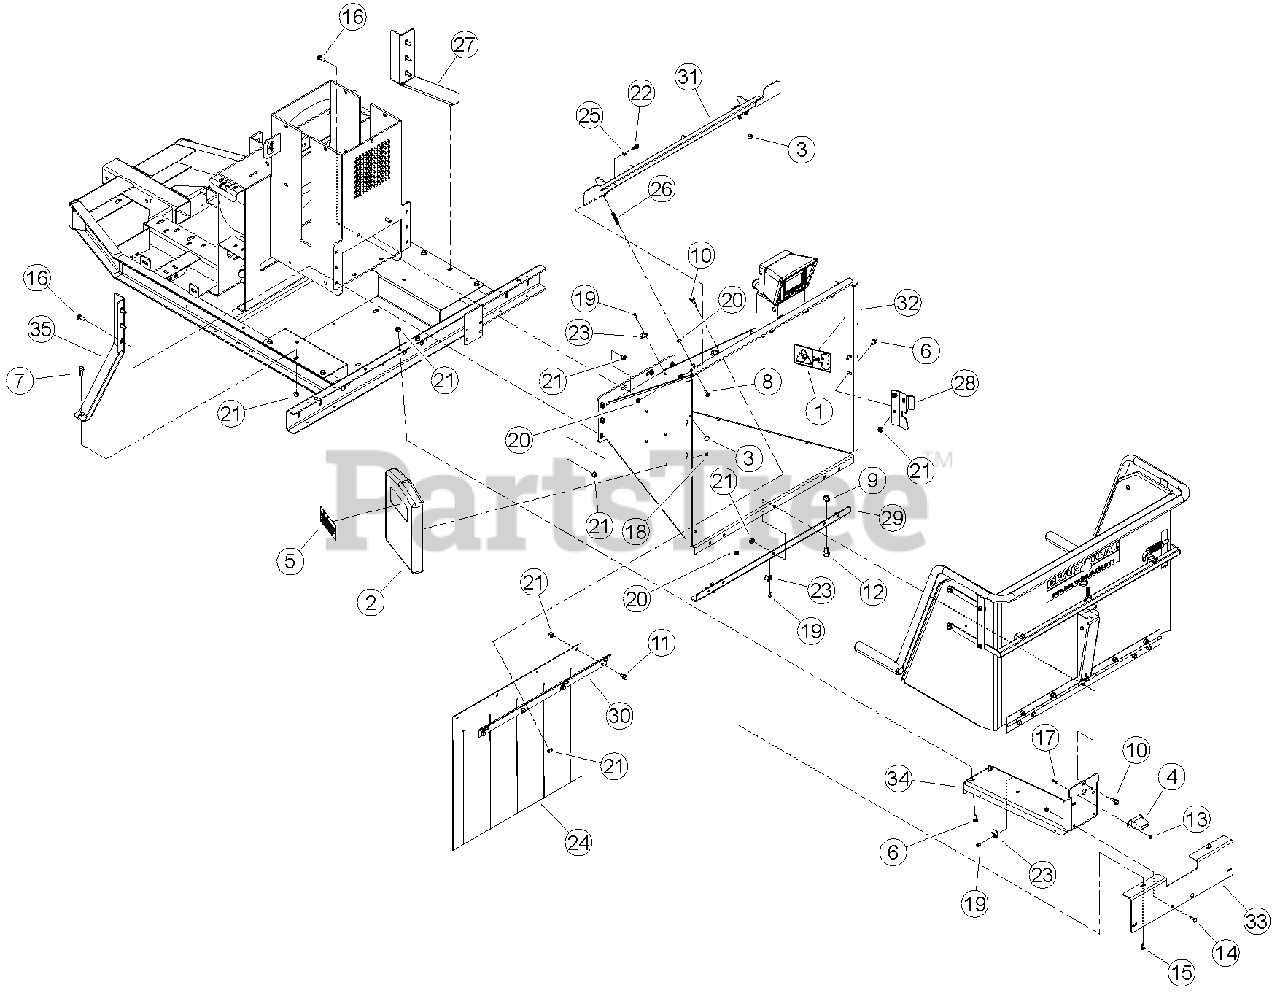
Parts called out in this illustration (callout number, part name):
1	DECAL, BLADE DANGER ISO
2	CONTAINER, INSTR. MANUAL
3	BUMPER, RUBBER
4	LIGHT, LICENSE PLATE
5	DECAL, MUTILINGUAL MANUAL
6	BOLT, 3/8 X 1" GR5 CRG NC ZP
7	BOLT, 3/8 X 1-1/4 FLANGE NC
8	BOLT, 5/16 X 3/4 FLANGE NC
9	NUT, 1/2-13 NYLOCK FLANGE
10	BOLT, 3/8 X 1 FLANGE NC
11	BOLT, 3/8 X 3/4 FLANGE NC
12	BOLT, 1/2-13 1.00 GR5 FLANGE NC
13	NUT, 8-32 NYLOCK
14	BOLT, 5/16 X 1" GR5 CRG ZP
15	BOLT, 5/16 X 3/4 GR5 CRG NC ZP
16	BOLT, 3/8 X 1-1/4" GR5 CRG NC ZP
17	SCREW, MCH 10-24 X 3/4" PAN HD PH ZP
18	RIVET, AL BLIND 1/4 X 1/2 DOME HEAD
19	RIVET, AL BLIND 1/4 X 3/4 DOME HEAD
20	NUT, 5/16-18 NYLOCK-FLANGE
21	NUT, 3/8-16 NYLOCK FLANGE
22	BOLT, 5/16-18 X 3/4 ZP FLANGE SHOULDER
23	CLAMP, CABLE MOUNT
24	FLAP, CHUTE
25	BEARING, .375 X .50 X .25 LONG
26	SPRING, COMPRESSION .437 DIA X 2.0 LONG
27	BRACKET, CHUTE SUPPORT RH
28	PLATE, TRAY LATCH
29	ANGLE, 6" INFEED SUPPORT
30	SUPPORT, 6" CHIPPER FLAP
31	WELDMENT, 6" TOP SAFETY BAR
32	WELDMENT, 6" DIESEL CHIPPER CHUTE
33	BRACKET, EUROPEAN LICENSE (CE COMPLIANT ONLY)
34	SUPPORT, CHUTE/SPARE
35	WELDMENT, PLATE LH SUPPORT
